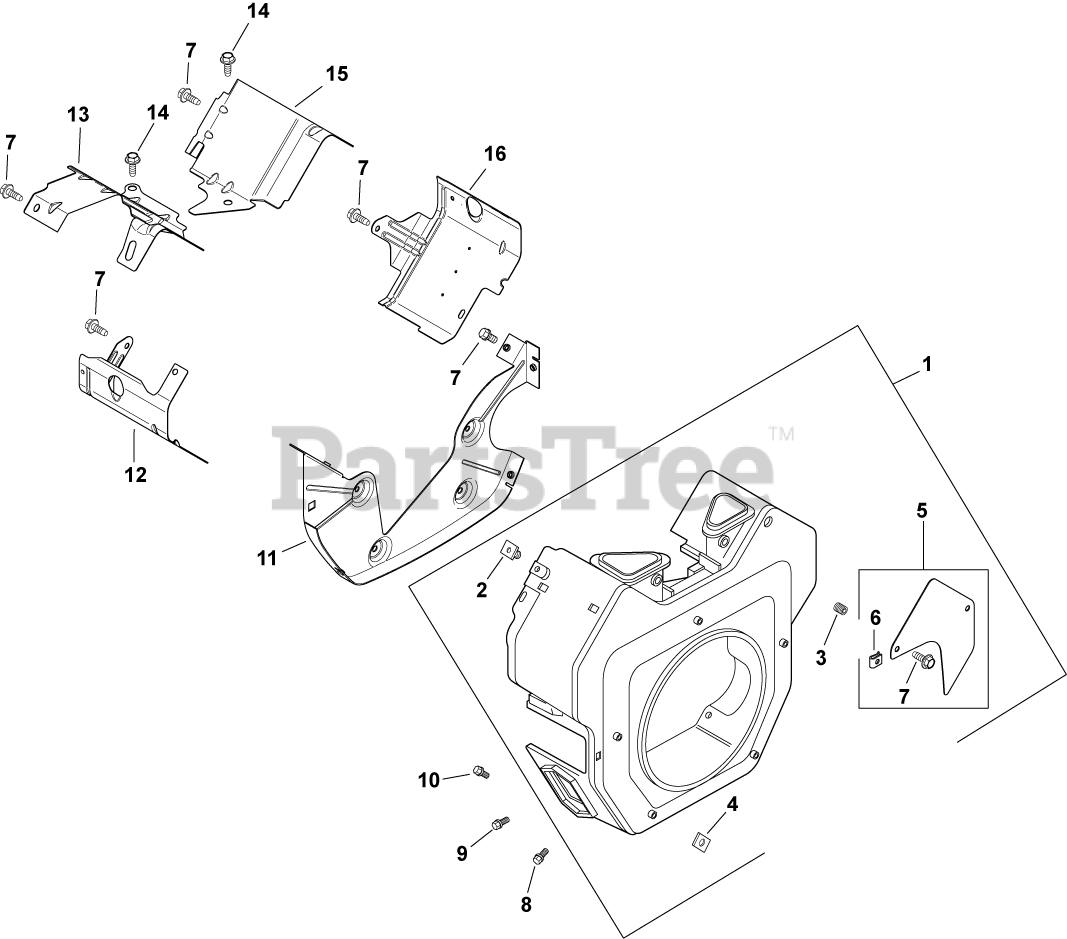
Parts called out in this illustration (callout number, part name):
1	BLOWER HOUSING ASSY-USE 84 027 03-S
2	NUT, PLASTIC
3	SCREW, SKT SET #10-24X1/4"
4	NUT, PLASTIC (KM)-USE 25 100 37-S
5	KIT, ACCESS PANEL USE 25 755 20-S
6	CLIP, MOUNTING-USE 25 154 13-S
7	SCREW,FLG THD FRM M6X1.0X16-(#25086397S)
8	SCREW,FLG THD FRM M5X0.8X16-(#25086398S)
9	SCREW - USE M-545016-S
10	SCREW, FLG THD FRM M5X.8X20-(#25086399S)
11	PLATE, BACKING-USE 24 146 59-S
12	BAFFLE,VALLEY #2SIDE(KM)-USE 24 063 88-S
13	BAFFLE, VALLEY #2 SIDE-USE 24 063 94-S
14	SCREW, FLG THD FRM M5X.8X10
15	BAFFLE, VALLEY (CH)-USE 24 063 93-S
16	BAFFLE, RIGHT BARREL-USE 24 063 85-S
